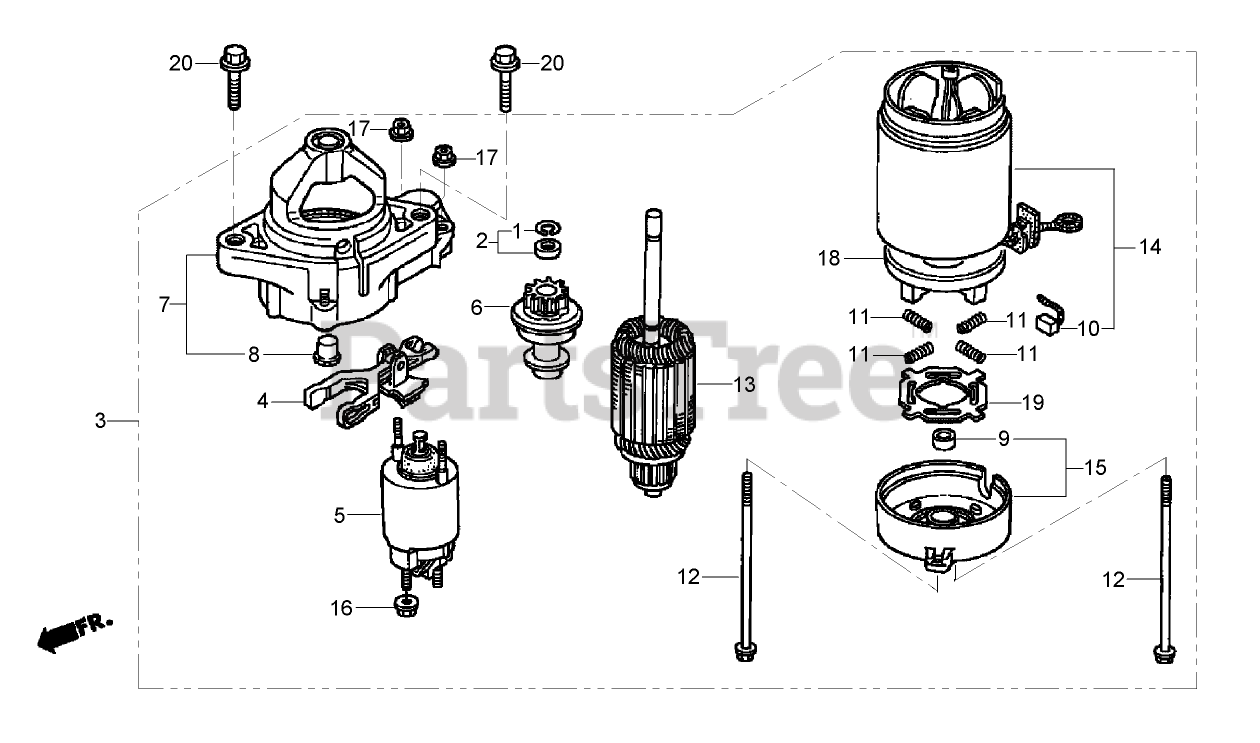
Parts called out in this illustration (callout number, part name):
1	RING-SNAP (DENSO)
2	CLUTCH STOP COLLAR SET
3	STARTER MOTOR ASM
4	LEVER-DRIVE, PINION
5	MAGNETIC SWITCH ASM
6	CLUTCH-OVERRUNNING
7	HOUSING-DRIVE SIDE
8	BEARING (A)
9	BEARING (B)
10	BRUSH
11	SPRING-BRUSH
12	BOLT-THROUGH
13	ARMATURE
14	YOKE
15	FRAME-END, COMMUTATOR
16	NUT-HEX (8MM)
17	NUT-FLANGE (5MM)
18	HOLDER-BRUSH
19	INSULATOR-HOLDER, BRUSH
20	BOLT-FLANGE (10X40)
